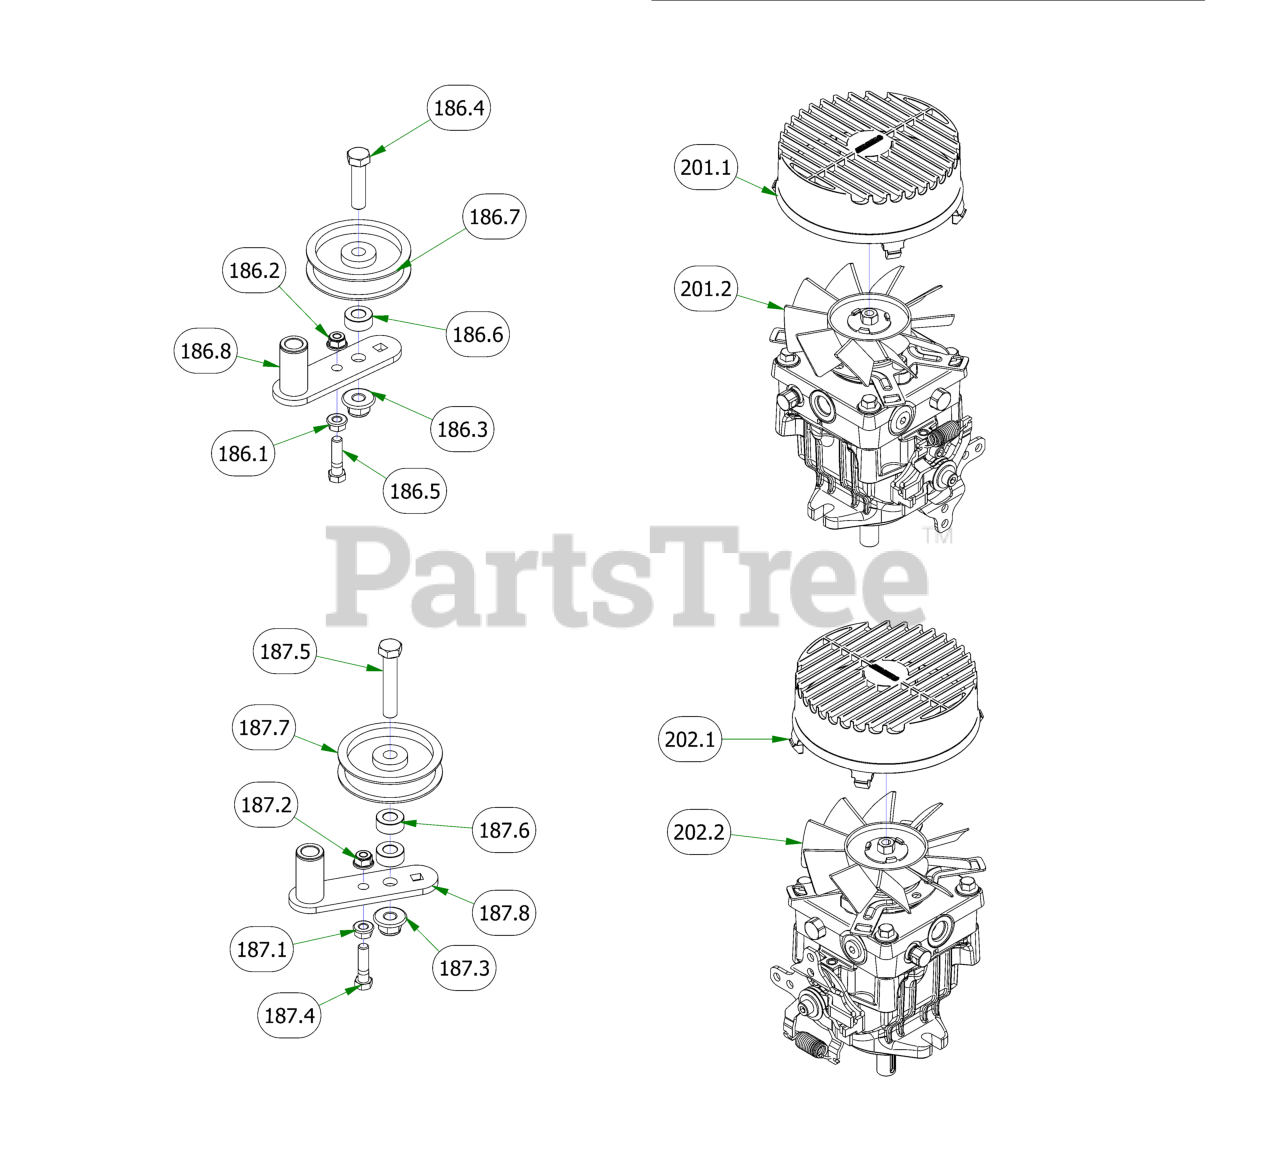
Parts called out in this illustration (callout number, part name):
186	2019 Renegade Belt Tensioner LH
186.1	3/8" Flange Nut
186.2	3/8" Nylock Flange Nut
186.3	1/2-13 Nylon Flange Nut
186.4	1/2-13x2 Grade 8 Hex Bolt
186.5	3/8" x 1 1/2" Hex Bolt
186.6	1/2 Solid Shaft Collar (W/1 Set Screw) Zinc
186.7	3.25 Flat Idler Pulley
186.8	Horizontal Idler Arm with Bushings
187	2019 Renegade Pump Belt Tensioner RH
187.1	3/8" Flange Nut
187.2	3/8" Nylock Flange Nut
187.3	1/2-13 Nylon Flange Nut
187.4	3/8" x 1 1/2" Hex Bolt
187.5	1/2" x 2 3/4" Hex Bolt
187.6	1/2 Solid Shaft Collar (W/1 Set Screw) Zinc
187.7	3.25 Flat Idler Pulley
187.8	Horizontal Idler Arm with Bushings
201	2019 Rogue/Renegade Left Pump 16cc
201.1	Fan Guard 6" - Fits Wheel
201.2	Hydro Fan - Light/Pup/Outlaw XP
202	2019 Outlaw Renegade Right Pump 16cc
202.1	Fan Guard 6" - Fits Wheel
202.2	Hydro Fan - Light/Pup/Outlaw XP
